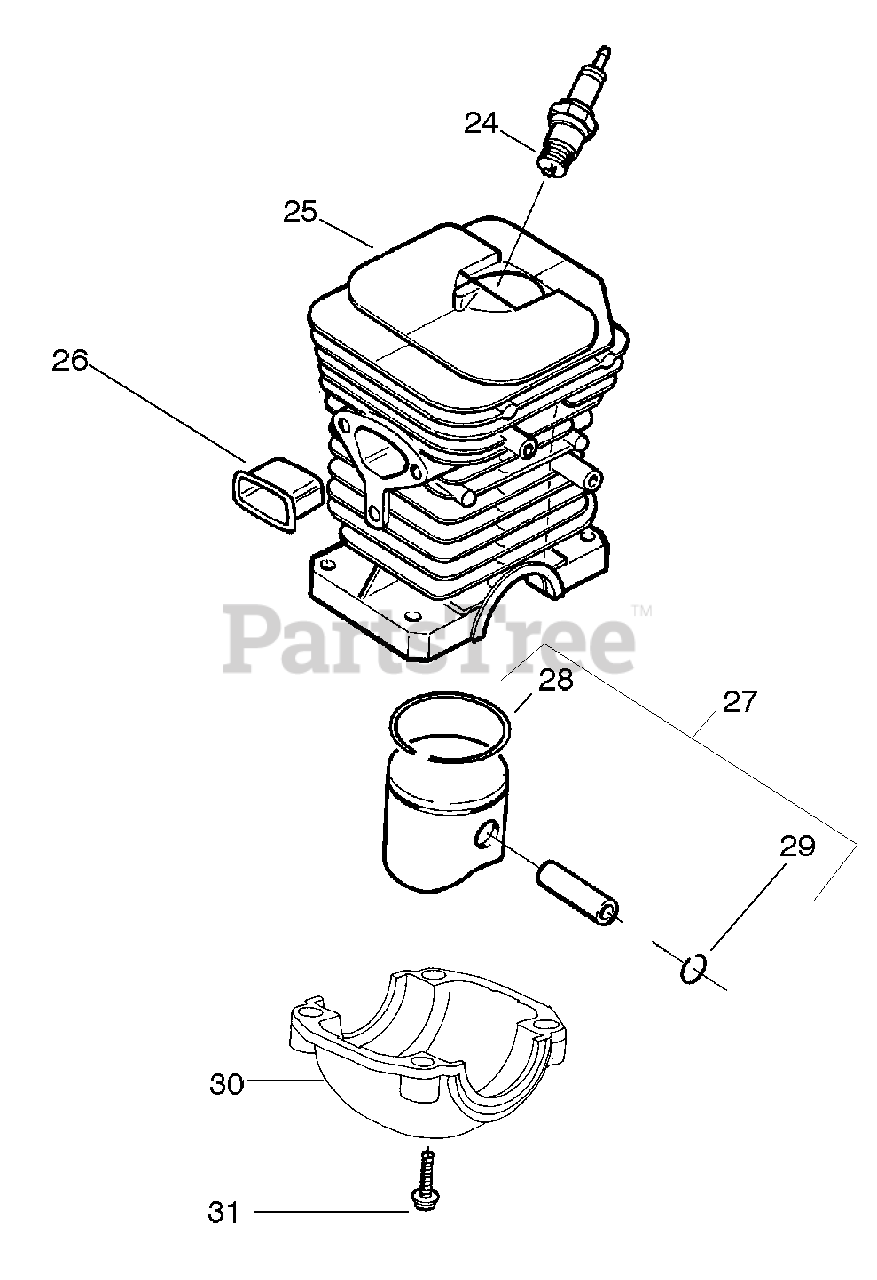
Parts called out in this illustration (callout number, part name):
24	Spark Plug
25	Kit-Cylinder
26	Insulator-Heat
27	Piston Kit
28	Ring-Piston
29	Piston Pin Retainer
30	Cap-Crankcase
